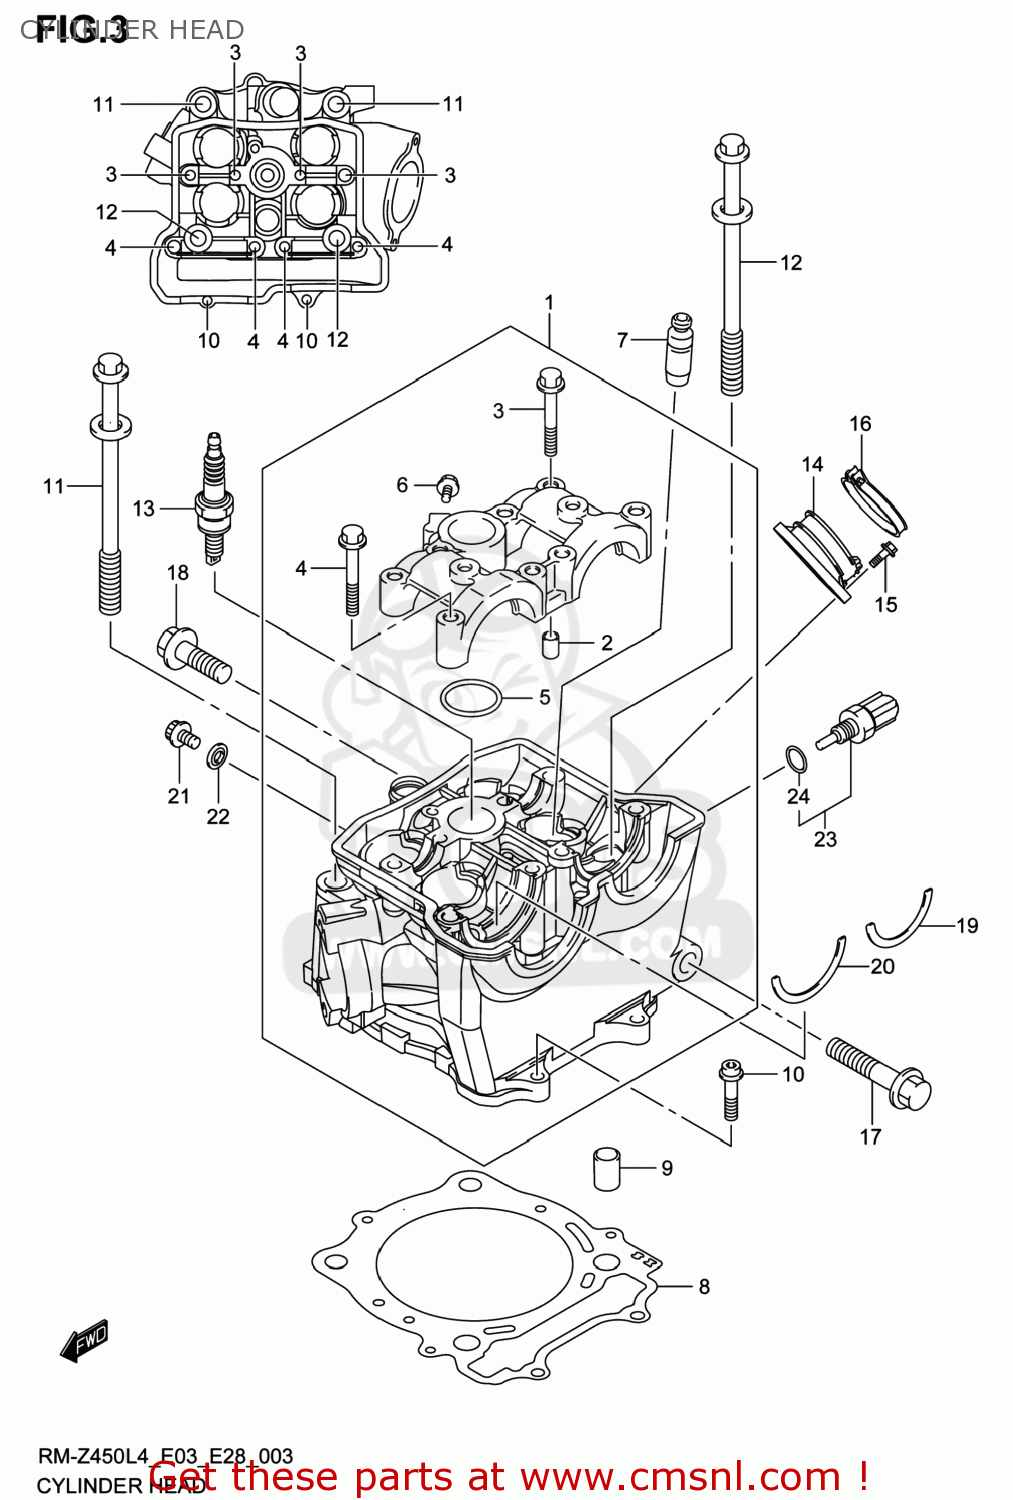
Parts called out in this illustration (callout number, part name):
1	HEAD ASSY,CYLINDER
2	PIN(6.2X8X11)
3	BOLT(6X40)
4	BOLT(6X45)
5	O RING(D:2.4,ID:25.7)
6	BOLT(6X10)
7	GUIDE,VALVE(OS:0.3)
8	GASKET,CYLINDER HEAD (NAS)
9	PIN
10	BOLT
11	BOLT,CYLINDER HEAD(L:140)
12	BOLT,CYLINDER HEAD(L:120)
13	PLUG,SPARK(DIMR8A10)
14	PIPE ASSY,INTAKE
15	BOLT
16	CLAMP,INTAKE PIPE
17	BOLT(10X43)
18	BOLT(10X32)
19	C RING,CAMSHAFT
20	C RING,CAMSHAFT
21	BOLT
22	GASKET(5.8X13X1.2) (NAS)
23	SENSOR,WATER TEMP
24	O RING
